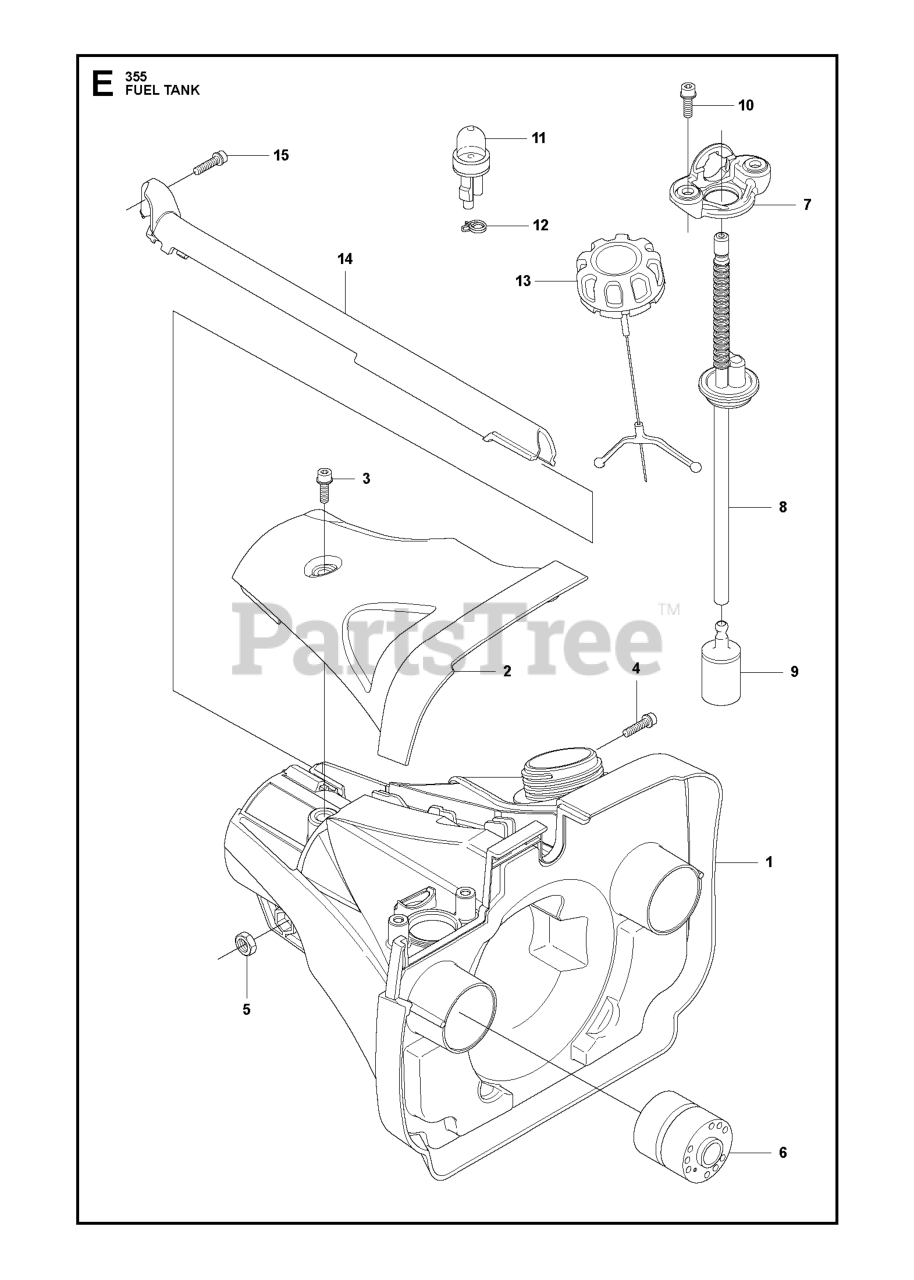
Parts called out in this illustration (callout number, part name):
2	COVER
3	SCREW IHSCFM
6	ANTIVIBE ELEMENT
9	RP FUEL FILTER
11	AIR PURGE BUBBLE
12	HOSE CLAMP
14	WIRING PROTECTION
15	SCREW IHSCFM
